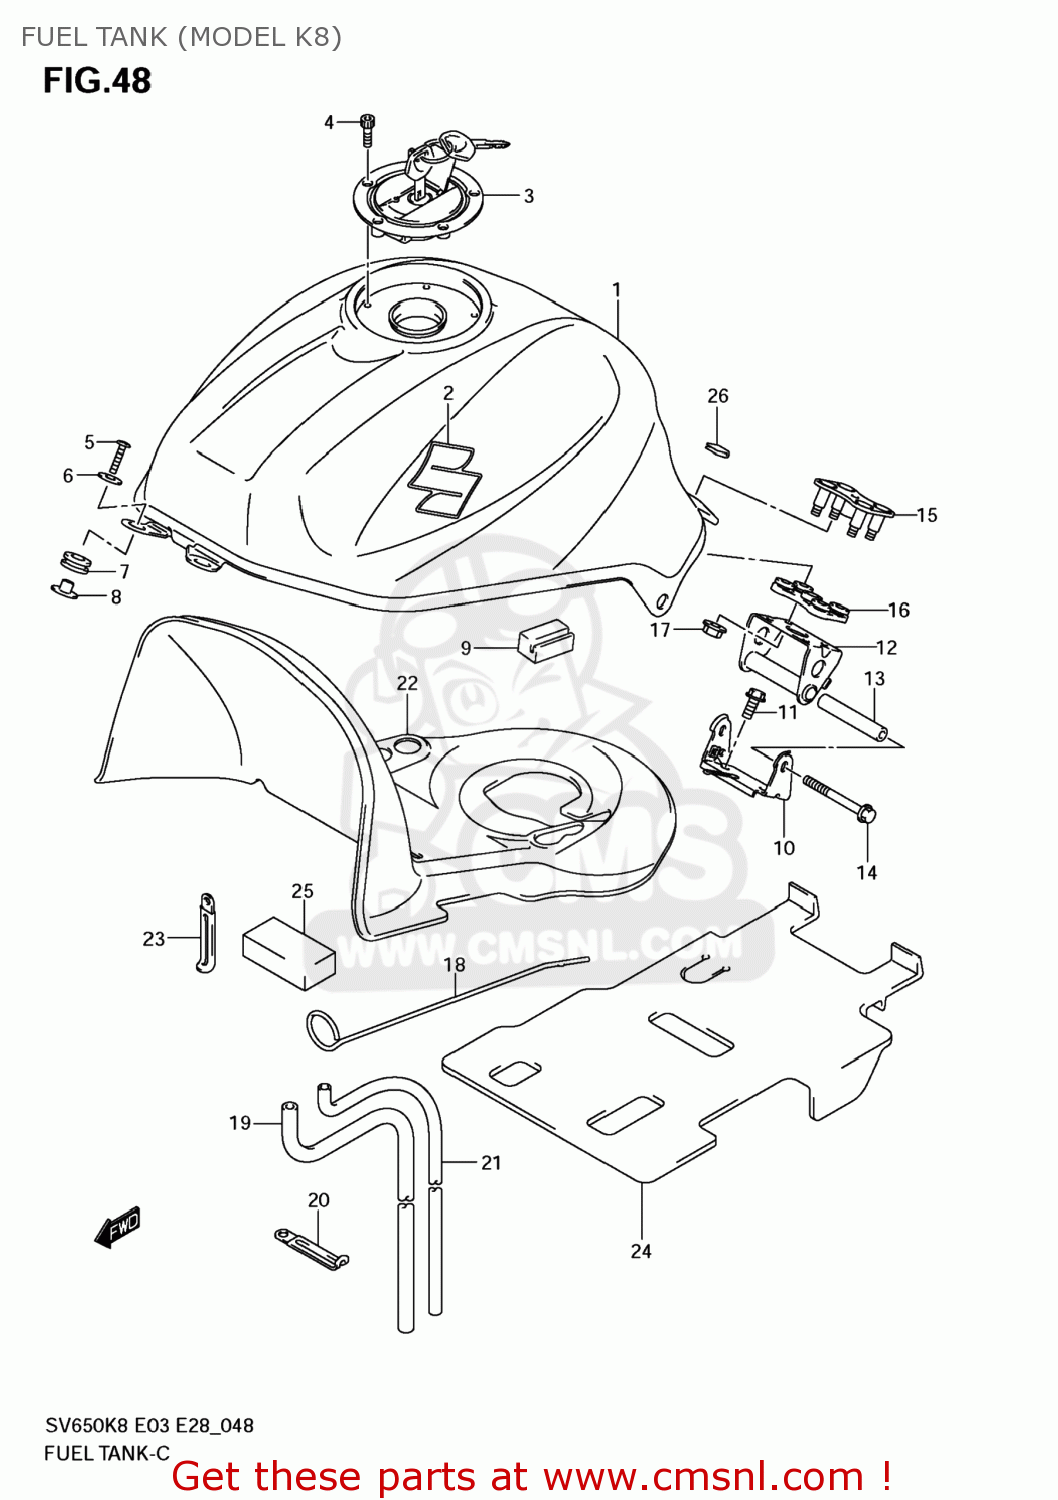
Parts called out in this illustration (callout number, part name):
1	TANK ASSY,FUEL(GRAY)
2	EMBLEM,S
3	CAP SET,FUEL TANK
4	BOLT(5X20)
5	SCREW(6X25)
6	WASHER(6.5X22X1.6)
7	CUSHION,FUEL TANK FR
8	SPACER,FUEL TANK FR
9	CUSHION,FUEL TANK SIDE
10	BRACKET,FUEL TANK NO.2
11	BOLT
12	BRACKET,FUEL TANK NO.1
13	SPACER,FUEL TANK RR
14	BOLT(6X100)
15	BRACKET,FUEL TANK RR UP
16	CUSHION,FUEL TANK RR
17	NUT
18	STAY,FUEL TANK
19	HOSE,WATER DRAIN
20	CLAMP(L:80)
21	HOSE,FUEL TANK
22	SHIELD,FUEL TANK HEAT
23	CLAMP(L:80)
24	SHEET,HEAT SHIELD RUBBER
25	CUSHION,FUEL TANK
26	MOLDING
